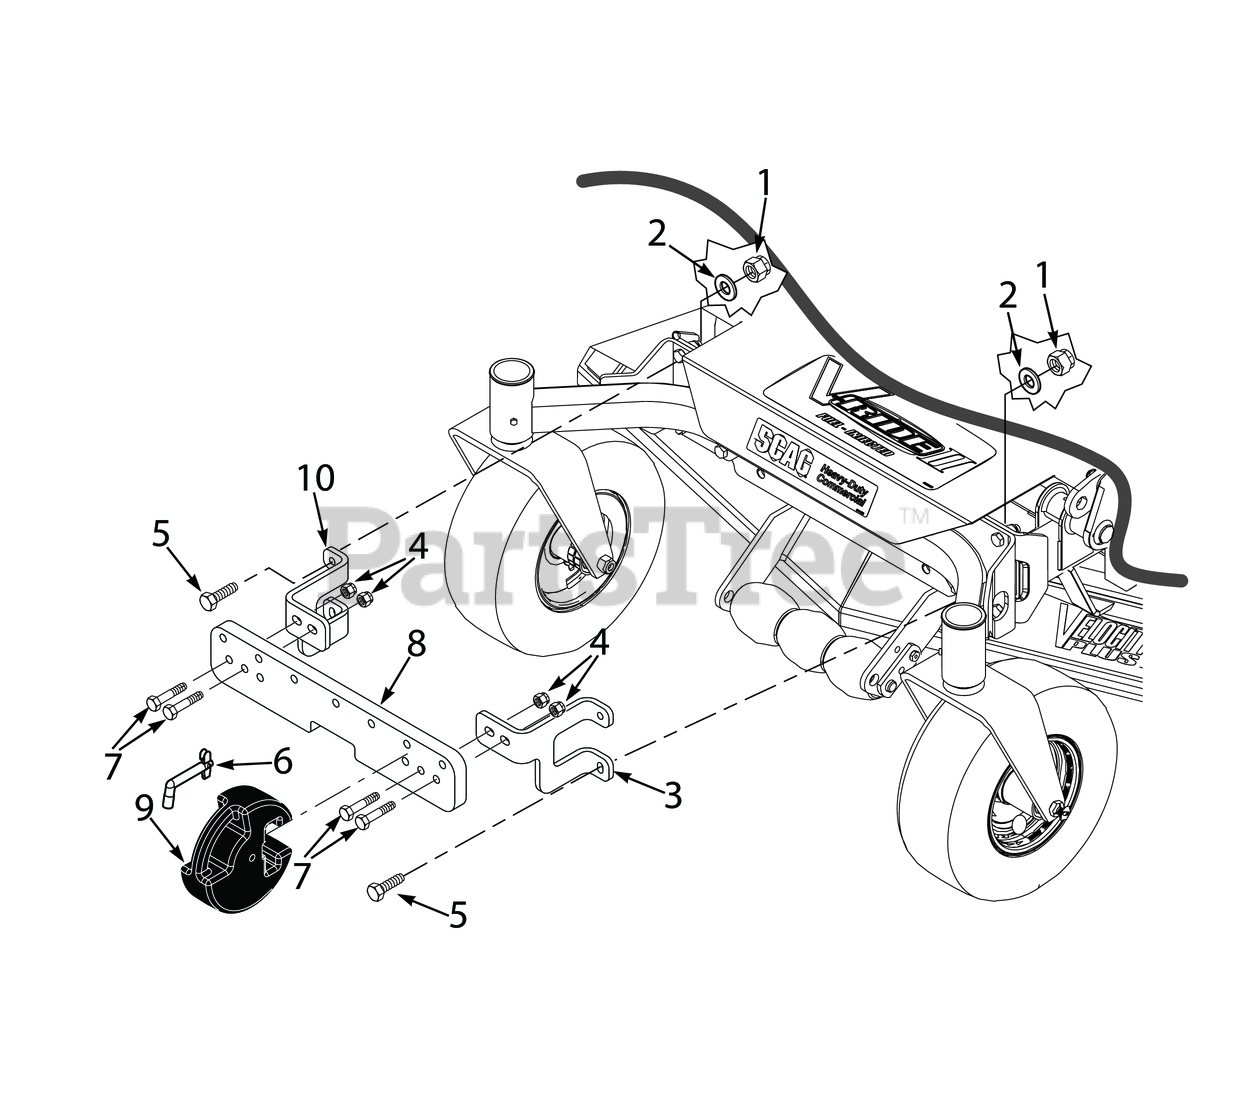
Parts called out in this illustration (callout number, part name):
1	HEX LOCKNUT, ELASTIC STOP, 7/16-14
2	Lockwasher, 7/16� Spring
3	Mounting Bracket, Weight Bar - LH
4	Nut, Elastic Stop 1/2-13, (STT-52 & STTII-52)
5	BOLT, HEX HEAD, 7/16-14 X 1-3/4
6	Pin, Weight Retention
7	Bolt, Hex Head 1/2-13 x 2-1/4"
8	Weight Bar
9	Weight
10	Mounting Bracket, Weight Bar - RH
